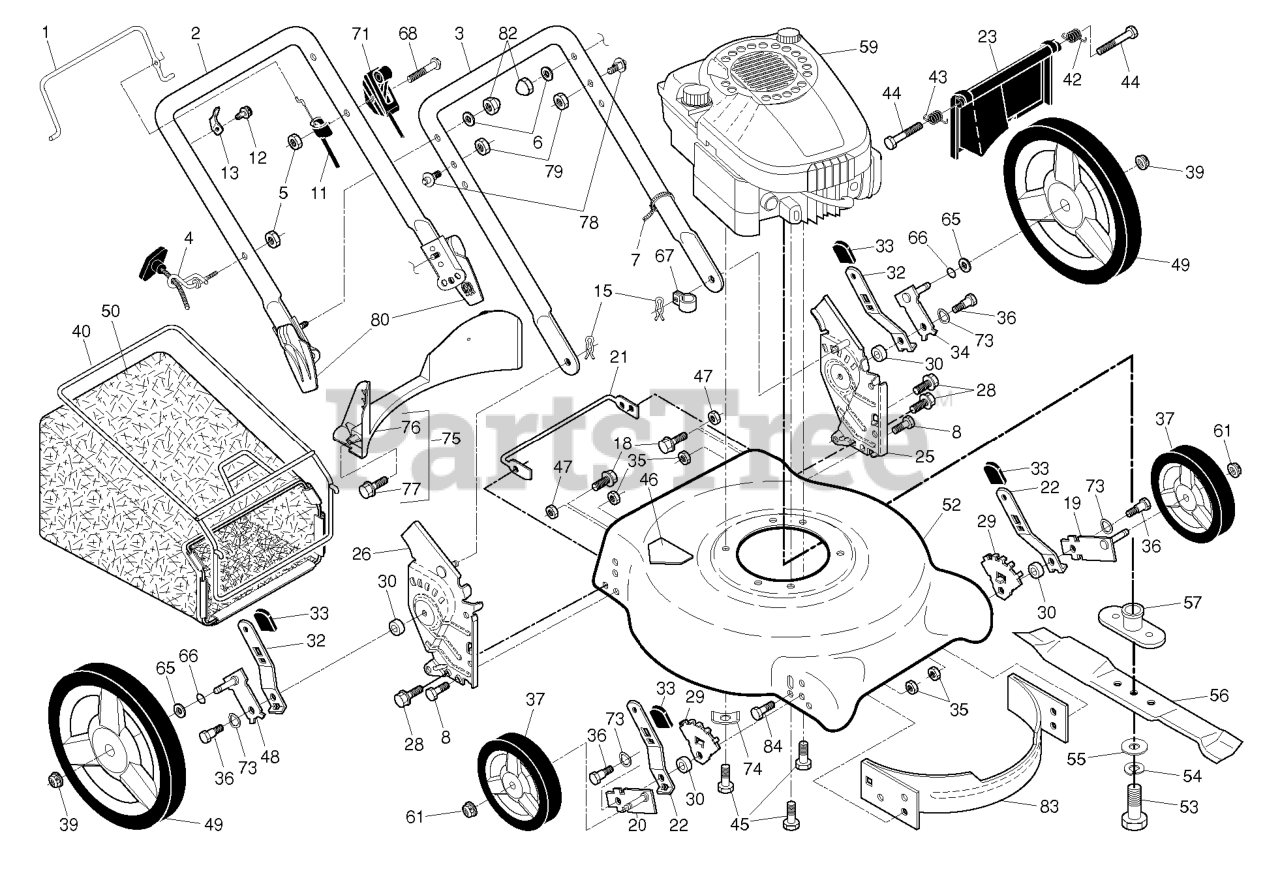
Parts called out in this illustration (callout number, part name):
1	BAIL.MZR.STD.ORANGE
3	HANDLE.LOWER.ECON.PNT
4	RB GUIDE.ROPE.STD.BLK.ZIN WSL
5	NUT
6	WASHER.20X8.5
7	TIE GUIDE
8	BOLT.FIN.HEX.5/16-18X3/4
11	CABLE.MZR.B&S.45.LT.PUSH
13	BRACKET.UPSTOP.RT
15	HAIRPIN COTTER
18	SCREW 1/4X20
19	AXLE ARM ASSY FRONT LH
20	AXLE ARM ASSY FRONT RH
21	FOOT.GUARD.21.DOM/FGD.CE.10
22	SELECTOR SPRING, FRONT
23	REAR DOOR ASSY
25	RP BRKT.ASM.HAND.HW.21.LT.ORNG
26	RP BRKT.ASM.HAND.HW.21RT.ORNG
28	SCREW 14-20 X 5/8
29	WHEEL ADJ BRACKET FRONT
30	SPACER.HEIGHT.ADJUSTER
32	SPRING.SEL.EXT.21.DOMED.12/14
34	AXLE ARM ASSY REAR LH
35	NUT.FLANGE.HEX.5/16X18.BLACK
36	SHOULDER BOLT 5/16-18
37	WHEEL AND TIRE ASSY, REAR
39	NUT.HEX.FLANGE.3/8-16.LOCKNUT
40	FRAME.BAG.21.REAR.DOMED.PUSH
42	SPRING.LH.22.REAR.DOOR.EZ.EMPT
43	SPRING.RH.22.REAR.DOOR.EZ.
45	BOLT 3/8-16X1-1/8
46	DECAL.INTERNATIONL.CUTFINGER
48	AXLE ARM ASSY REAR RH
49	RP.WHEEL.12X1.75H 3 SPOKE.RAD
52	KIT.HSG.21RD.DOME.ORG.CE
53	SCREW, HEX HD 3/8-24 X 1-3/8
54	LOCKWASHER
55	WASHER,HARDEN
56	BLADE.21.PUSH
57	ADAPTER.BLADE.W/KEY.25MM.CE
61	NUT.HEX.FLANGE.3/8-16.LO(3 2)
65	WASHER.FLAT.1/2
66	O-RING..070X.487.NEOPRENE
67	CLIP.CABLE.BLK
73	WASHER.CURVED.CYLINDRICAL
74	WASHER.ENGINE.BZP
75	KIT.BAFFLE.REAR.PLASTIC.21.RD
76	BAFFLE.REAR.PLASTIC.21.RD.ECON
77	SCREW.HX.13X.750
78	STUD.QUICK.ADJUST
79	NUT.LOCK.5/16-18
80	QUICK.ASM.RELEASE.BLACK
82	Locknut, Hex 1/4-20
83	BAFFLE.FRONT.21.DOME.US
84	BOLT.5/16HEX.WHS.HD
